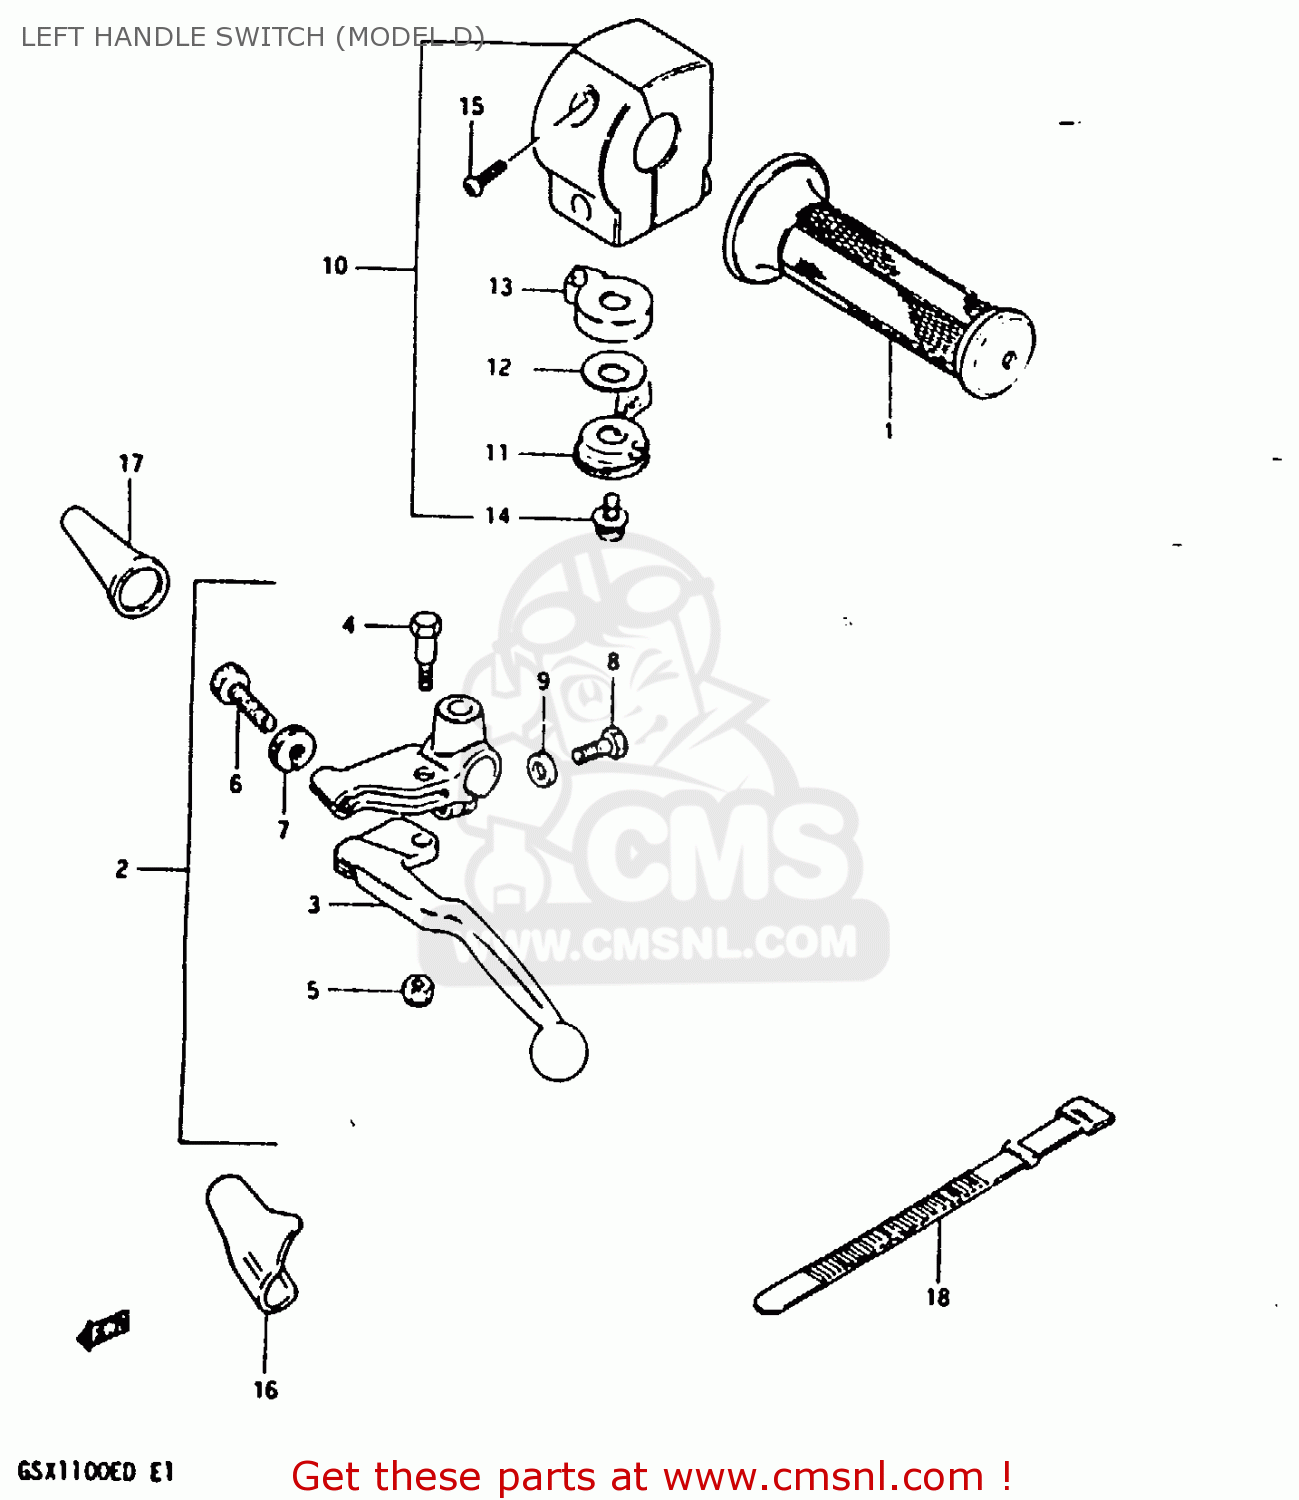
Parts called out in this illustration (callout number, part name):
1	GRIP,L
2	LEVER ASSEMBLY,CLUTCH
3	LEVER,CLUTCH
4	BOLT,LEVER
5	NUT 6MM
6	ADJUSTER,CABLE
7	NUT,CABLE ADJUSTER LOCK
8	BOLT,CLUTCH LEVER HOLDER
9	SPACER
10	SWITCH ASSY, HANDLE LH
11	LEVER,STARTER
12	WASHER,ADJUSTER
13	BODY,STARTER LEVER
14	SCREW,CHOKE LE
15	SCREW
16	COVER,CLUTCH LEVER
17	BOOT,CLUTCH CABLE
18	CLAMP(L:120)
